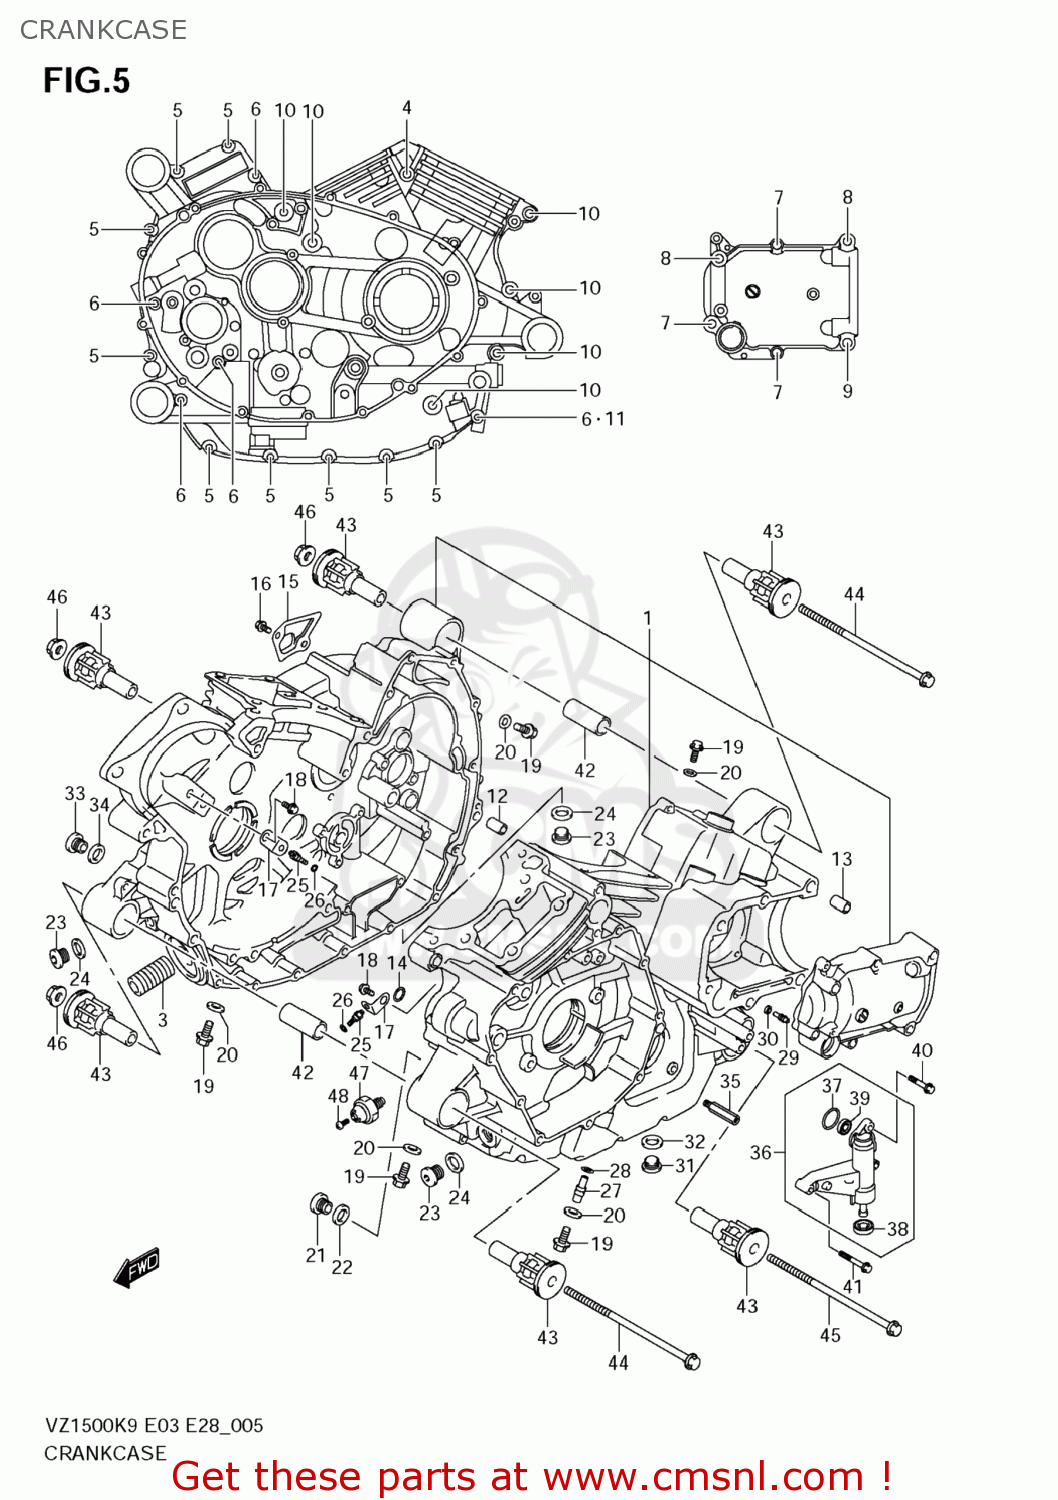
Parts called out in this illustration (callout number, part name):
1	CRANKCASE SET
2	BEARING,CRANK THRUST
3	UNION,OIL STAND
4	BOLT(8X110)
5	BOLT
6	BOLT
7	BOLT
8	BOLT
9	BOLT
10	BOLT
11	GASKET(5.8X13X1.2) (NAS)
12	PIN,CRANKCASE
13	PIN(8.4X11X20)
14	O-RING
15	PLATE,OIL SEPARATOR
16	BOLT
17	PLATE,PISTON JET RR
18	BOLT
19	BOLT
20	GASKET(8.2X14X1) (NAS)
21	PLUG(10X10)
22	GASKET(10X14X3.6) (NAS)
23	PLUG,16X8
24	GASKET(16X22X2) (NAS)
25	JET,PISTON COOLING(0.8)
26	O RING(D:1.2,ID:4)
27	JET(12)
28	O RING(D:1.2,ID:4)
29	JET,OIL GALLERY(18)
30	O RING(D:1.2,ID:4)
31	PLUG(14X20)
32	GASKET(13.8X18.8X4.8) (NAS)
33	PLUG,14X12
34	GASKET(13.8X18.8X4.8) (NAS)
35	BOLT,SEC DRIVE UNIT COVER
36	CAMSHAFT SET,CLUTCH RELEASE
37	O RING(D:2.5,ID:21)
38	SEAL,OIL(10X20X6)
39	SEAL,OIL(10X17X5)
40	BOLT
41	BOLT
42	SPACER,ENG MTG
43	BUSH,ENGINE MOUNTING
44	BOLT 10X215
45	BOLT(10X195)
46	NUT
47	SWITCH ASSY,OIL PRESSURE
48	BOLT,OIL PRESSURE SWITCH
